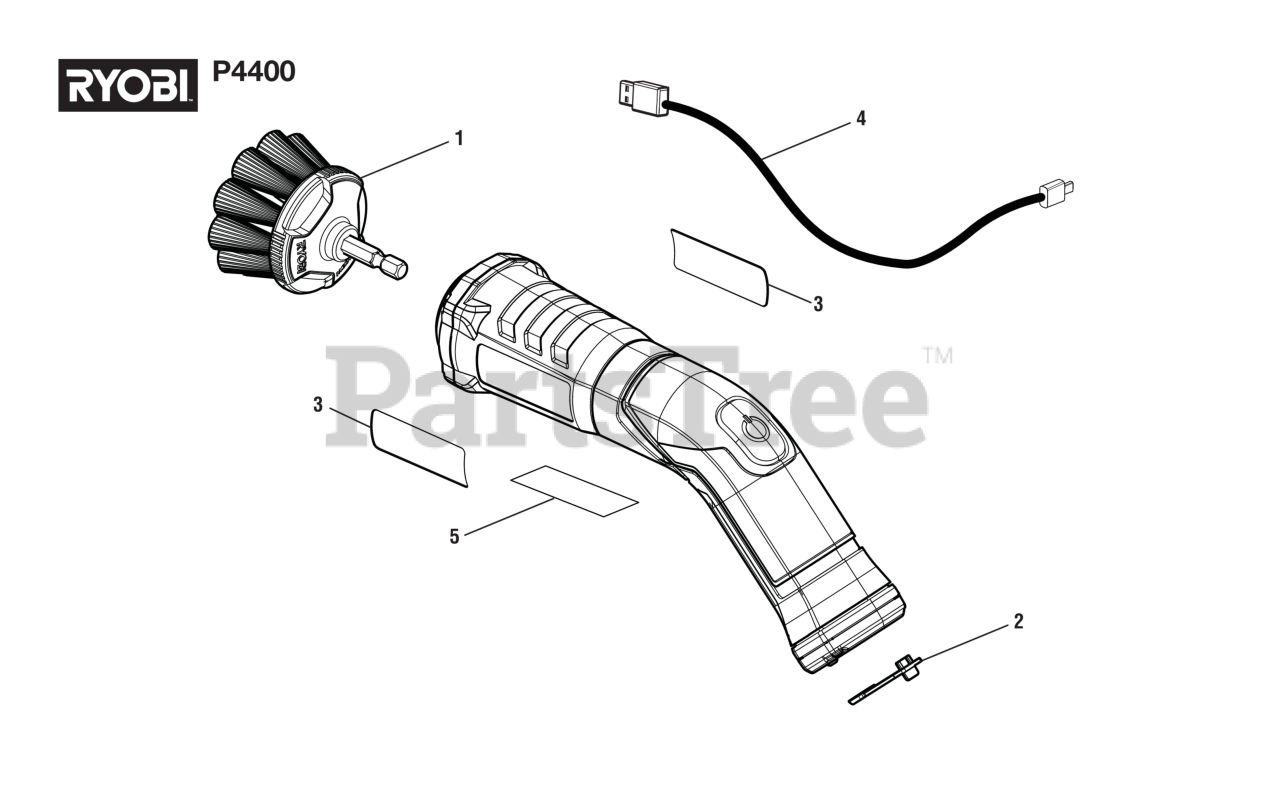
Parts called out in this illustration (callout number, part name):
2	USB Plug Cover
3	Logo Label
4	USB Cable
5	Data Label
